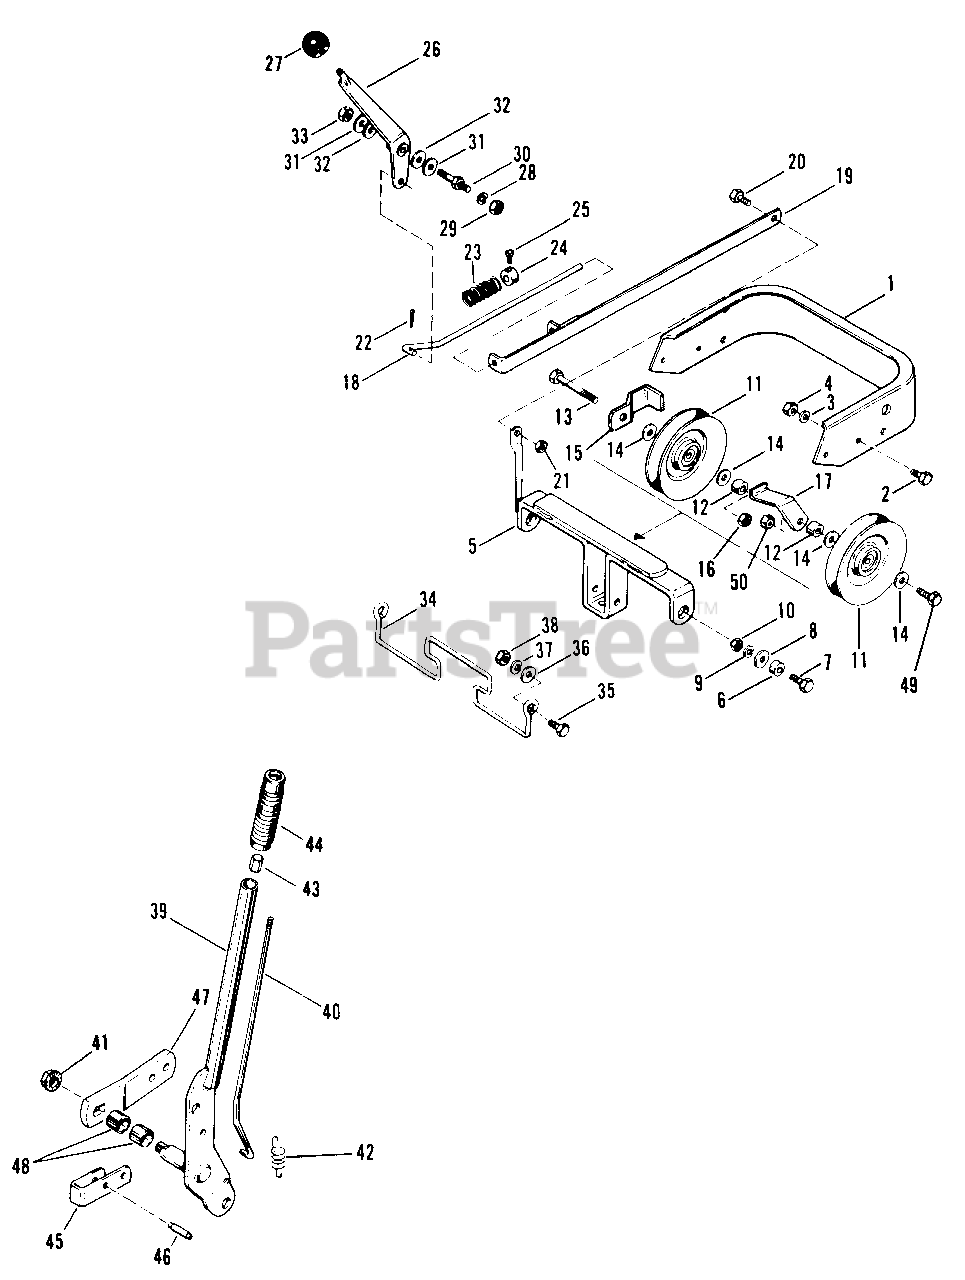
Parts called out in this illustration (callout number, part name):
1	Bumper, Front
2	Capscrew, Hex, 5/16"-18 x 3/4" lg.
3	Lockwasher, 5/16"
4	Nut, Hex, Full, 5/16"-18
5	Clevis Assembly, Pulley
7	Capscrew, Hex, 3/8"-16 x 1" lg.
8	Washer, Plain, 3/8"
9	Lockwasher, 3/8"
10	Nut, Hex, Full, 3/8"-16
13	Capscrew, 3/8-16 x 1-3/4" lg.
14	Washer, Plain, 3/8"
15	Stop, Belt
16	Nut, Hex, Full, Lock, 3/8"-16
18	Rod, Clutch, P.T.O.
19	Guide Assembly, Idler
20	Capscrew, Hex, 3/8"-16 x 3/4" lg.
21	Nut, Hex, Full, Lock, 3/8"-16
22	Pin, Cotter, 3/32" x 5/8" lg.
24	Collar, Set
25	Screw, Set,1/4"-20 x 3/8" lg.
26	Lever Assembly
28	Lockwasher, 5/16"
29	Nut, Hex, Full, 5/16-18
31	Washer, Plain, 5/16"
32	Washer, Special
33	Nut, Hex, Full, Lock, 5/16"-18
34	Stop, Belt, P.T.O.
35	Capscrew, Hex, 5/16"-18 x 3/4" lg.
36	Washer, Plain, 5/16"
37	Lockwasher, 5/16"
38	Nut, Hex, Full, 5/16"-18
39	Lever Assembly, Lift
40	Rod, Latch
41	Nut, Flange, Lock 1/2"-13
43	Button, Thumb
44	Grip, Lift Lever
45	Latch, Lift Lever
46	Pin, Roll, 3/8" x 1" lg.
47	Link, Lift Lever
49	Capscrew, Hex, 3/8-24 x 2" lg.
50	Nut, Hex, Full, Lock, 3/8-24
